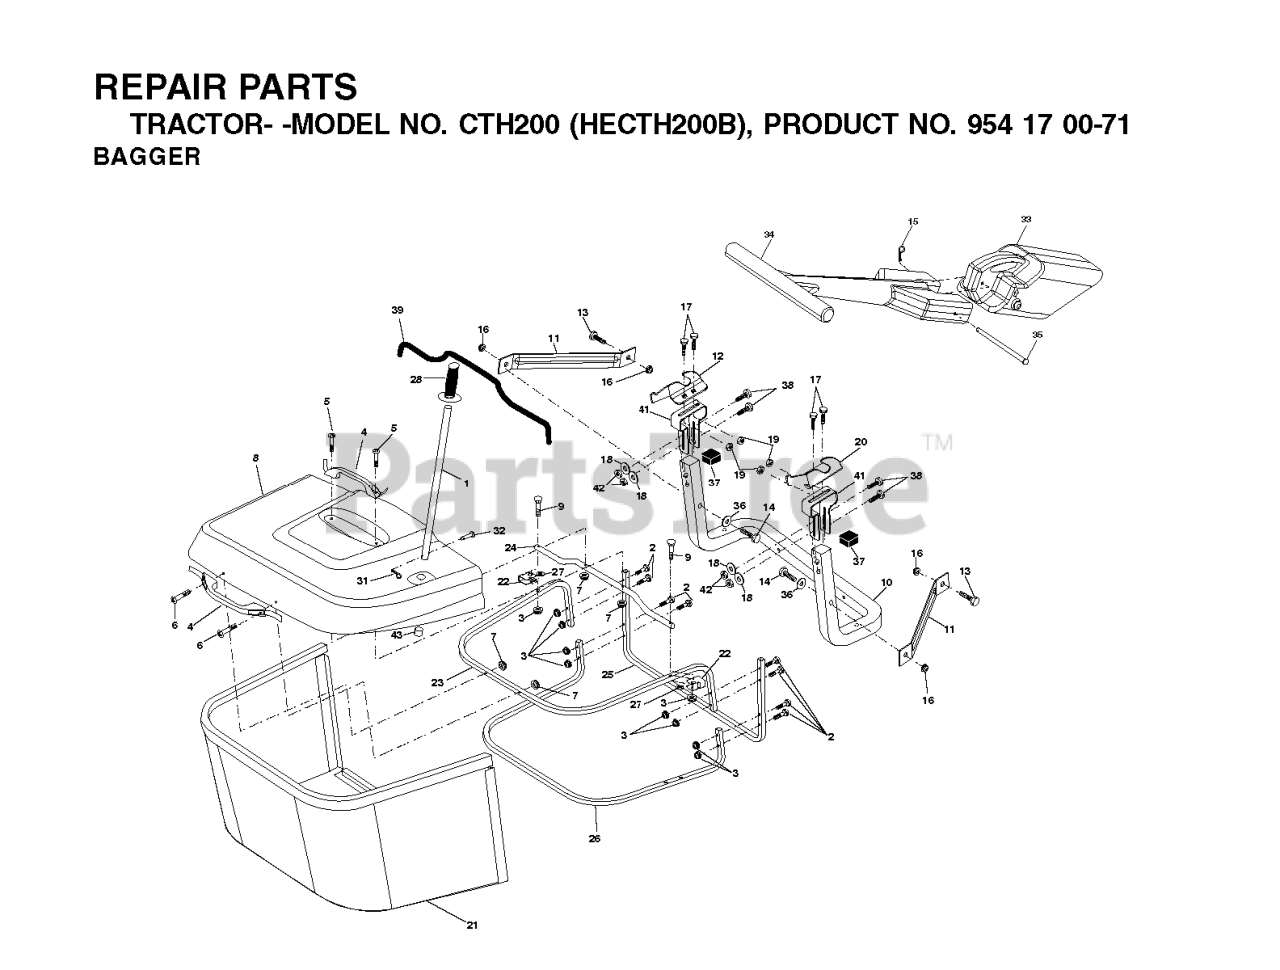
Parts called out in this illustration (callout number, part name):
1	TUBE HANDLE
2	Bolt Carriage 1/4-20 x 2.0 Gr.5
3	NUT T
4	HANDLE.BAGGER.W/LVRS.BLK.CRD
5	SCREW.PAN.HEAD
6	REPL BY 532 75 00-29
8	COVER.PNT.BGR.CRD.WSLOTS.MS668
9	Bolt Carriage 1/4-20 x 2.25d x Gr.5
10	TUBE
11	BRACKET.SUPPORT.UPPER.BAG.CRD
12	BRACKET
14	BOLT-HEX EAK
15	RETAINER-SPRNG RB
16	NUT LOCK FLG 3/8-16 UNC
17	RP BOLT 5/16-18 X3/4 ZN/YEL GR
18	WASHER M
19	NUT LOCK HEX FLANGE 5/16-18
20	BRACKET
21	GRASS BAG
22	BRKT.SIDE.BAG.CRD
23	TUBE.UPPER.BAG.CRD
24	TUBE.PIVOT.BAG.CRD.BLACK
26	TUBE.LOWER.BAG.CRD
27	BUSHING
28	GRIP.HANDLE.BLACK
31	RETAINER M
32	RIVET,DRILLED
33	MULCH PLUG, CTH150
34	HANDLE.MULCHER.92.CRD (2 2)
36	WASHER
37	Plug Support Bagger CRD
38	BOLT.5/16-18X2.5
39	SEAL.TRIM.37'
41	BRKT.VERT.ADJ.BAGGER.CRD
42	NUT.71038.31-18.HEX.NYLOCK
43	PLUG, TUBING END
